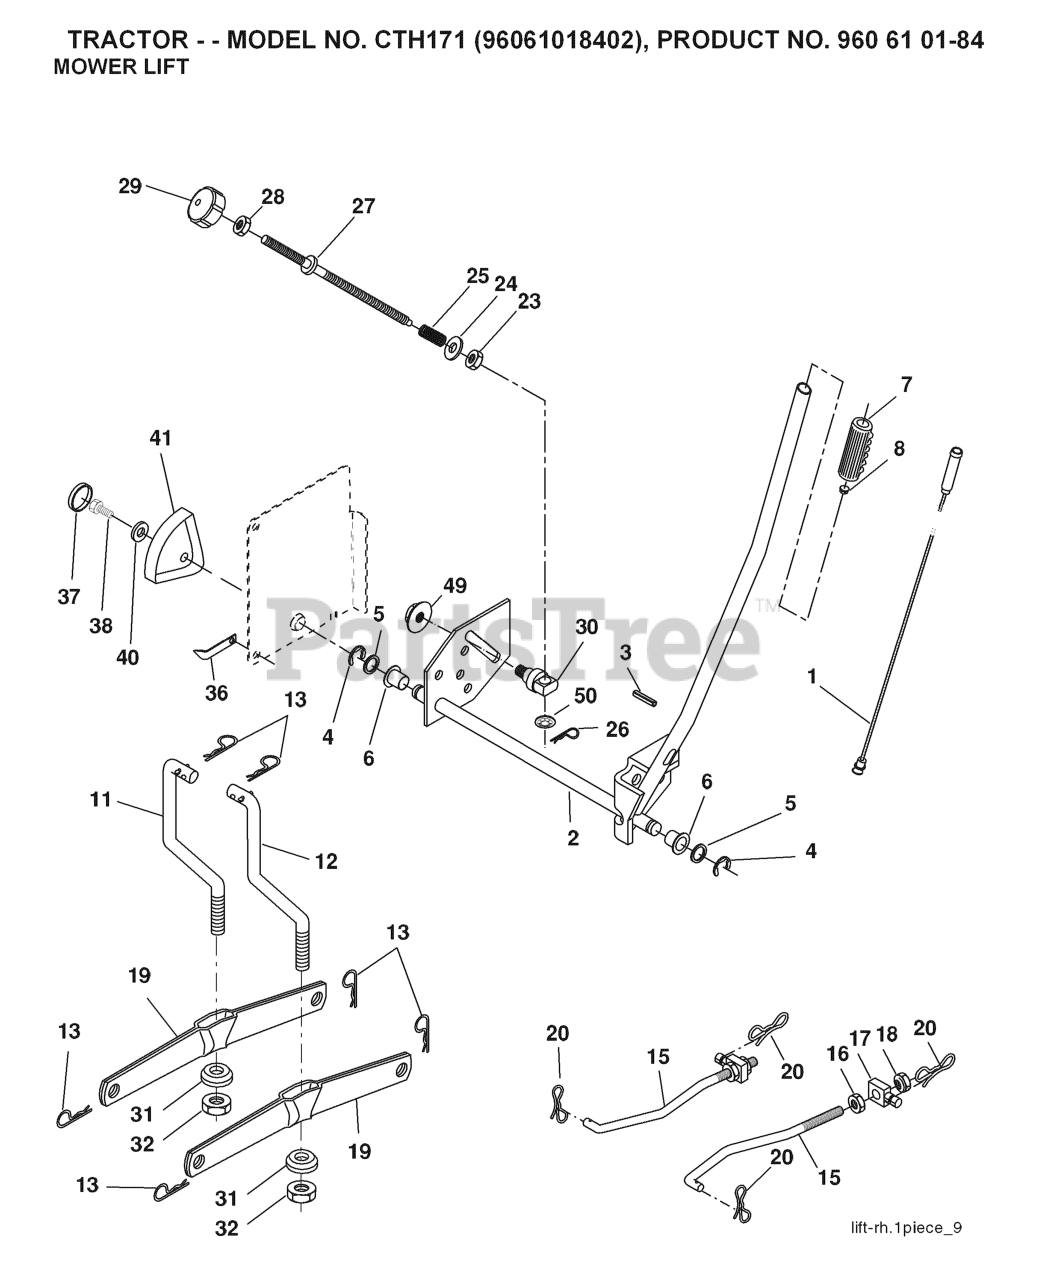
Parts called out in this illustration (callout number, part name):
1	WIRE ASM INNER W/ PLUNGER LT
2	SHAFT ASM R HANDLE
3	PIN GROOVE.
4	RETAINING RING LT
6	BEARING.NYLON
7	GRIP HANDLE
8	REPL BY 532 12 59-25
11	LINK
12	LINK
13	RETAINER-SPRNG RB
15	LINK.SUSPENSION.FRONT
16	NUT.HEX.JAM.1/2-13
18	NUT.LK.W/WSH.1/2.
19	ARM.REAR.SUSPENSION
20	PIN.COTTER.7/16.BOW TI.
26	RETAINER CLIP
27	ROD ADJ LIFT
28	NUT
29	KNOB INF 3/8-16
31	BEARING.PIVOT.LIFT
32	NUT CROWNLOCK 3/8-24
36	POINTER, HEIGHT INDICATOR(2 2)
38	SCREW 5/16-18X1
41	HEIGHT INDICATOR
49	NUT
50	NUT PUSH M
